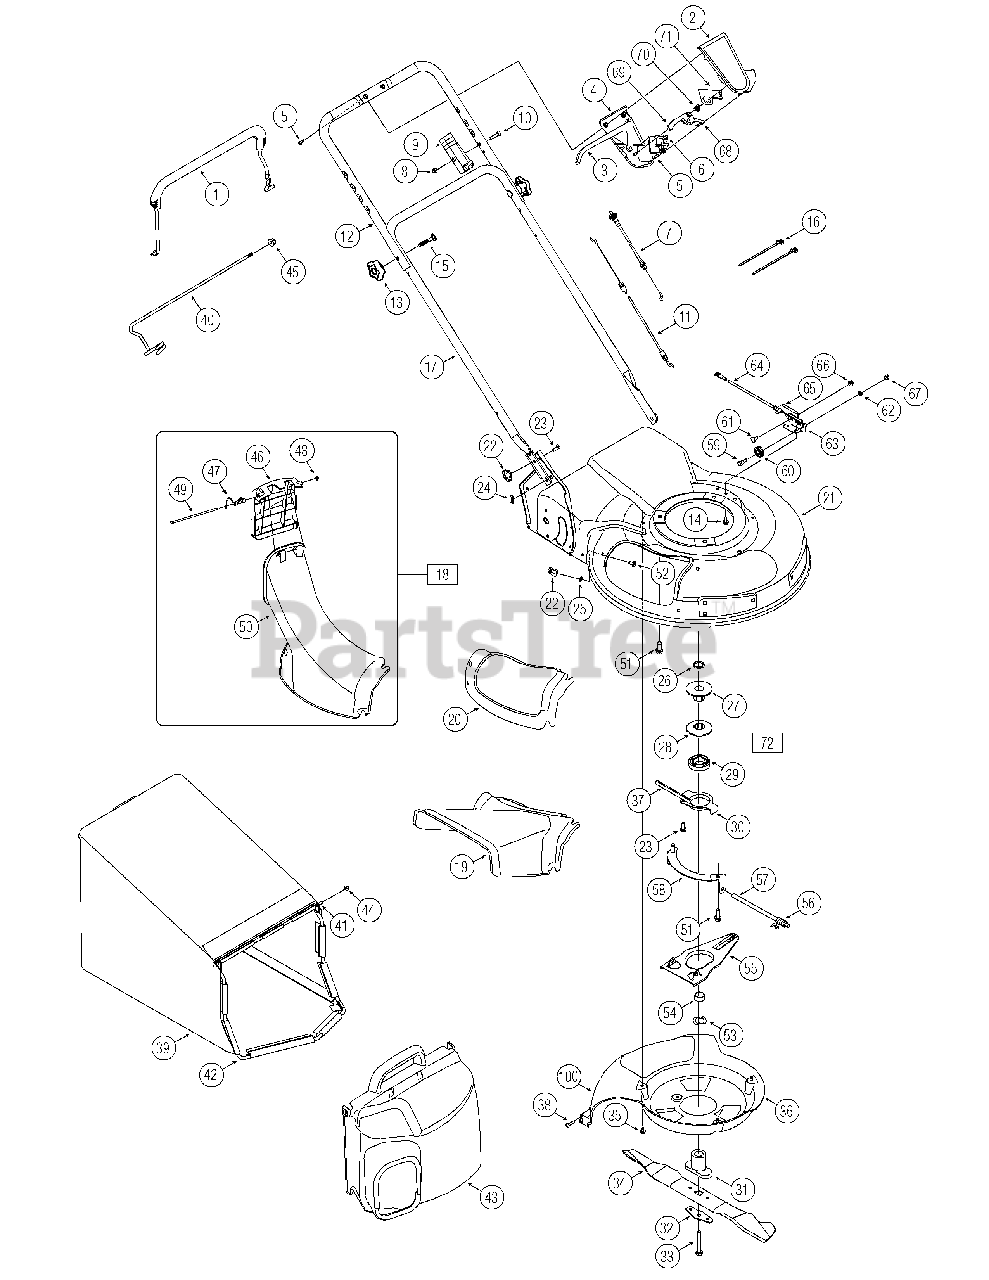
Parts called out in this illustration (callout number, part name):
2	Upper Control Housing
3	Drive Control
4	Lower Control Housing
5	C Sunk Tap Screw, #10
6	Cable Mounting Cap
7	Drive Cable - 51"
8	Top Lock Nut, 1/4-20
9	Control Housing
10	Oval C-Sunk Screw
11	Control Cable - 55"
13	Star Knob
14	Screw, 1/4-20 x .625
15	Carriage Bolt, 5/16-18 x 2.0
16	Cable Tie
18	Adapter Assembly
19	Side Discharge Chute
20	Mulch Cover
23	Carriage Bolt, 1/4-20 x .75"
25	Push Nut, .25 x ID x .50 OD
26	Sleeve Spacer, .88 ID x 1.13 OD
27	Half Pulley: 2.62 OD
28	Half Pulley: 2.62 OD x 1.61
29	Ball Bearing
31	Blade Adapter
32	Blade Bell Support
33	Hex Bolt, 3/8-24 x 2.5
34	21" Mulching Blade
35	Screw, 1/4-20 x 3.75
36	Baffle
37	Belt, 3/8 x 39.24
38	HL Screw, #12-16 x 1.00
39	Grass Catcher
41	Pivot Rod
43	Grass Catcher Cover
45	Hex Nut 5/16-18
46	Chute Door
47	Torsion Spring
50	Grass Catcher Adapter
51	Sems Screw, 3/8-16 x 1.00
52	Carriage Screw, 1/4-20 x .62
53	Wave Washer, 1.38 ID x .88 OD
54	Slve Spacer, .88 ID x 1.00 OD
59	Shlder Screw, .375 ID x 1/4-14
60	Cable Roller
61	Carriage Screw, 1/4-20 x .50
62	Lock Washer, 1/4
67	Hex Nut 1/4-28
68	Shift Lever Spring
69	6 Speed Shift Lever
70	Gear Insert
71	6 Spd. Rack Cable
72	Pulley Assembly
